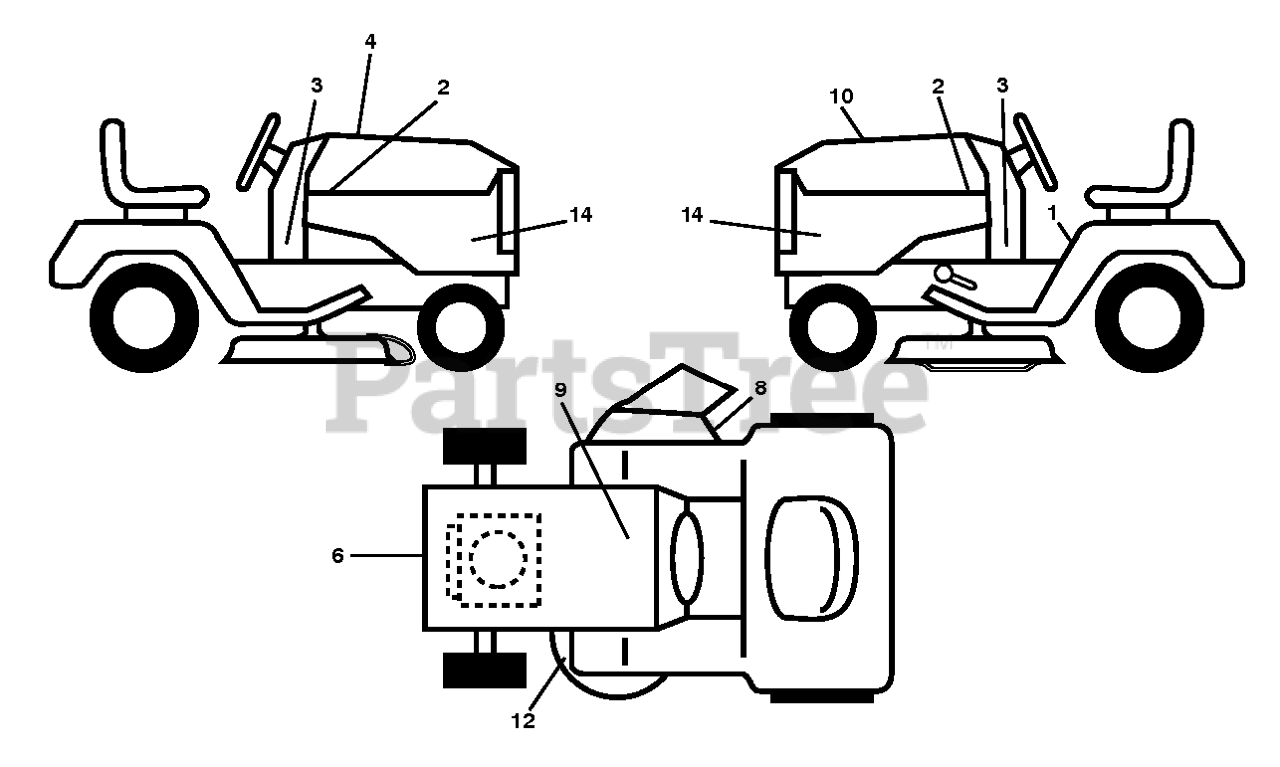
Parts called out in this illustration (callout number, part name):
1	DECAL.FENDER.WARNING.ENG
2	EMBLEM.HOOD.HUSQ.DEALER
3	DECAL.RPL.BSM44.ENDR.TGW.54K6
4	DECAL.RPL.BSM44.ENDR.TGW.54K6
6	DECAL.ENG.BSM44.ENDUR.27HP
8	DECAL.MOWER.SCH.48/54
9	DECAL BTRY SYMBOLS
10	DECAL HOOD CUST. RESP.
12	DECAL.WARN.KEEP.HAND.AWAY
14	DECAL.SDPNL.2754GLS.ENDUR.HUSQ
